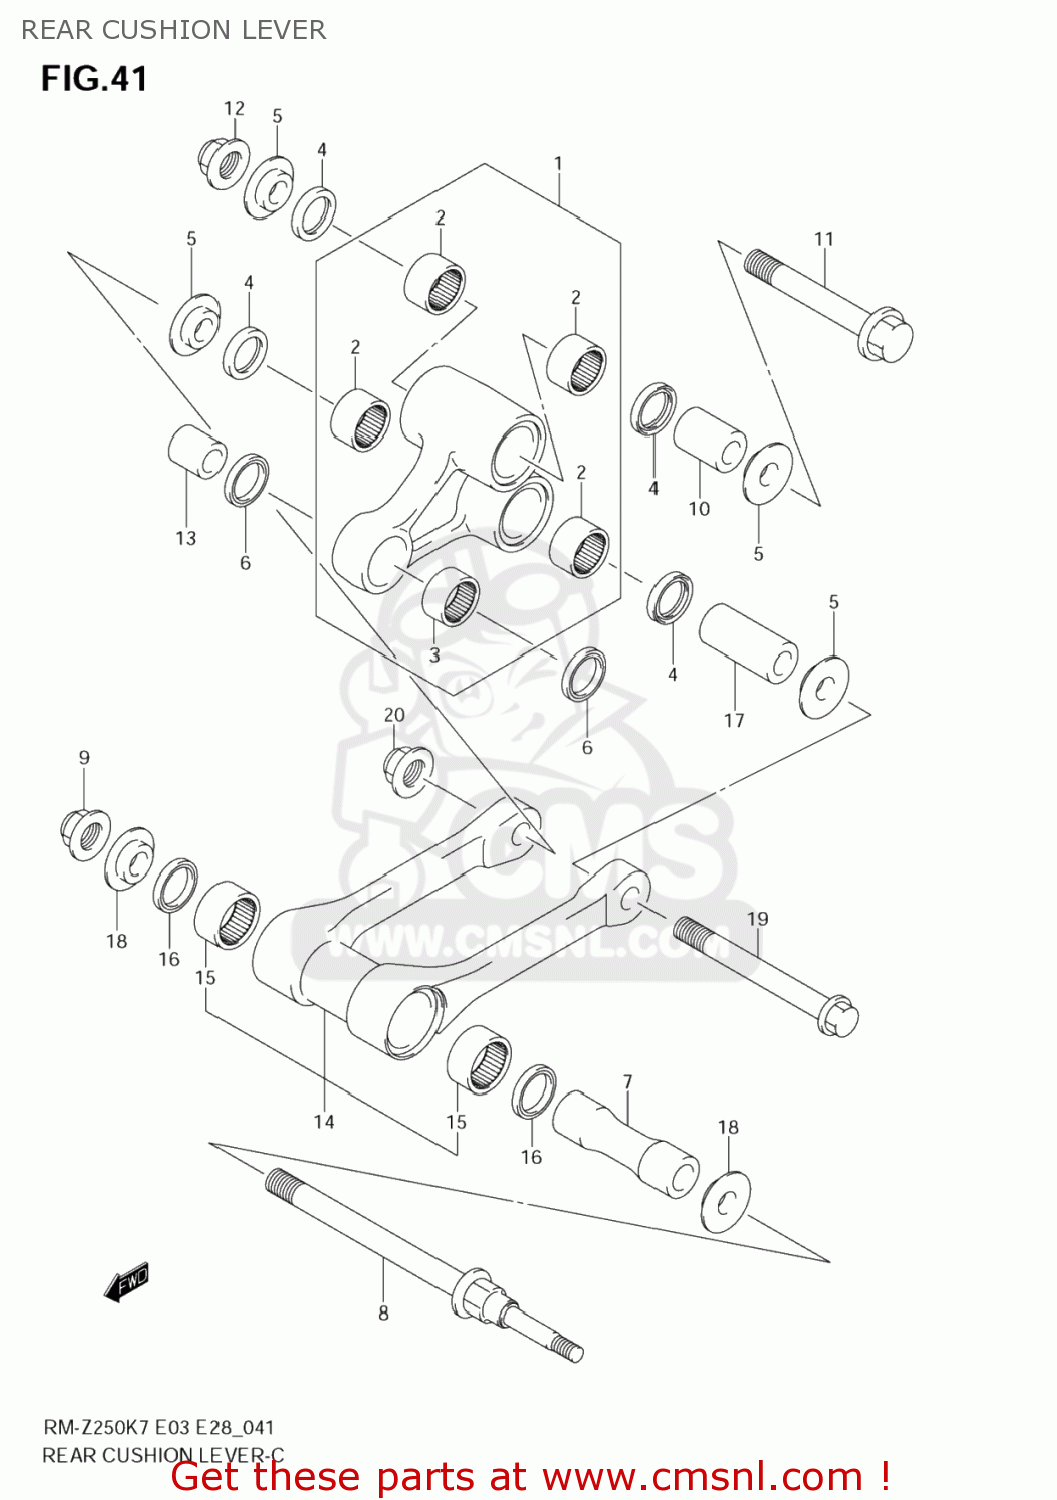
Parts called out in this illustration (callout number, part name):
1	LEVER SET,RR CUSHION
2	BEARING(20X26X14)
3	BEARING(20X26X12)
4	SEAL,OIL(20X26X4)
5	SPACER,RR CUSHION LEVER SIDE
6	SEAL,OIL(20X26X4.5)
7	SPACER,RR CUSHION ROD
8	BOLT,RR CUSHION ROD
9	NUT
10	SPACER,RR CUSHION LEVER UPPER
11	BOLT,RR CUSHION LEVER UPR
12	NUT
13	SPACER,RR CUSHION LEVER RR
14	ROD SET,RR CUSHION LEVER
15	BEARING(20X26X14)
16	SEAL,OIL(20X26X4)
17	SPACER,RR CUSHION LEVER LWR
18	SPACER,RR CUSHION LEVER SIDE
19	BOLT,RR CUSHION LEVER LWR
20	NUT
